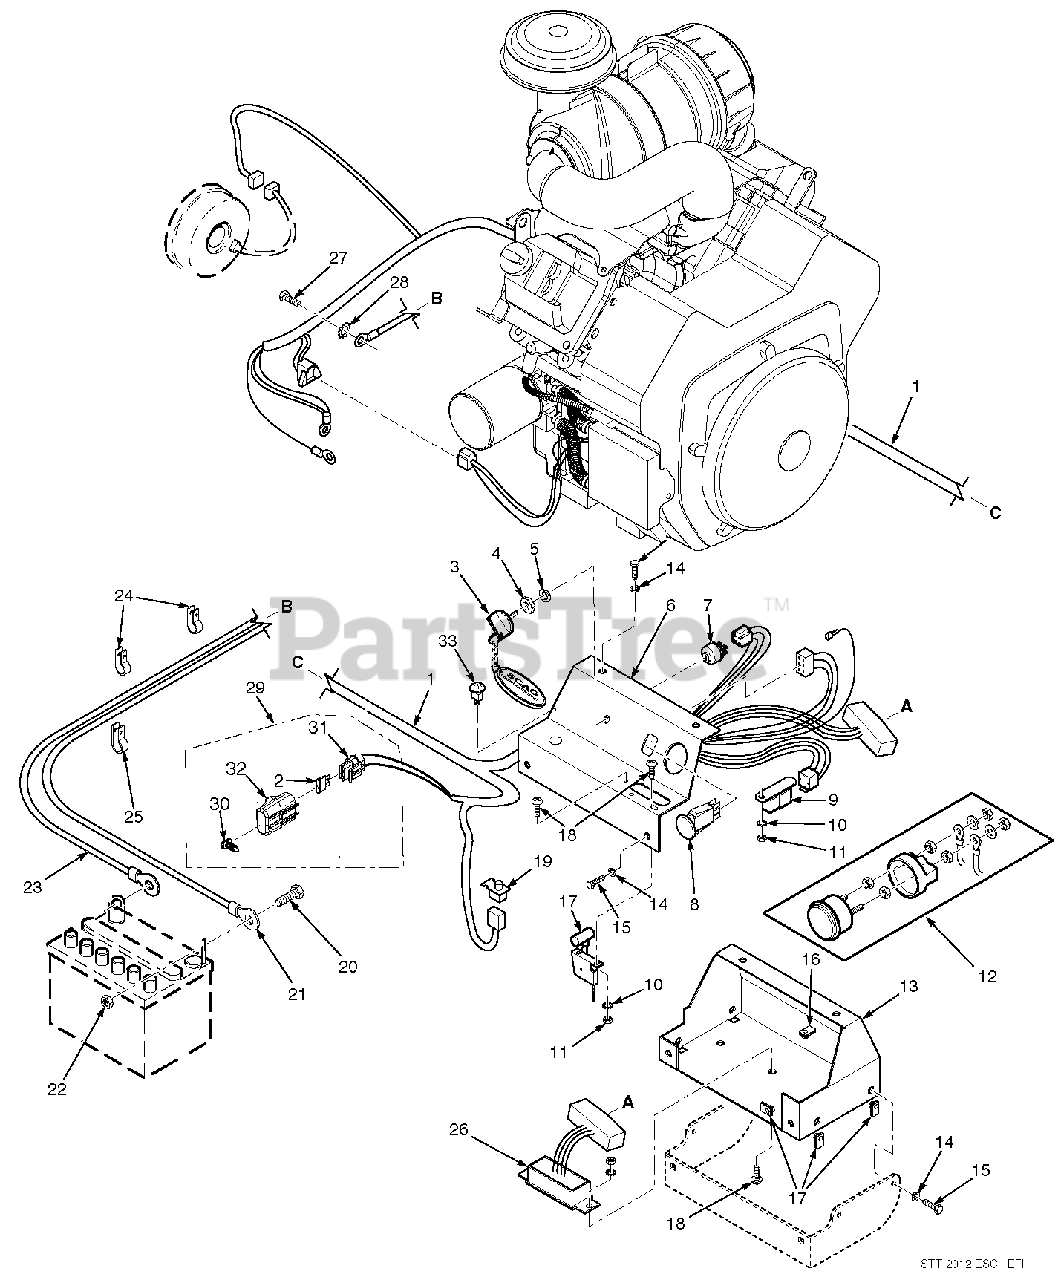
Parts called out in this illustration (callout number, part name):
1	Wire Harness
2	Fuse, 20 AMP
3	Key, Ignition
3	Key Assembly w/Fob
4	Nut, Hex 5/8-32
5	Lockwasher, 5/8" Internal
6	Instrument Panel, Top w/Decals
7	Key Switch
8	Switch, PTO
9	Relay
10	Lockwasher, #10 External Tooth
11	Nut, Hex #10-32
12	Volt Meter
13	Base, Instrument Panel
14	Lockwasher, 1/4"
15	Bolt, Hex Head 1/4-20 x 3/4"
16	U-Nut, 1/4-20
17	Throttle And Choke Controls
18	Screw, Phillips Washer Head #10-32 x 1/2"
19	Switch, Interlock-Seat
20	Bolt, Hex Head 1/4-20 x 1/2"
21	Cable, Battery - Red
22	Nut, Hex 1/4-20
23	Cable, Battery - Black
24	Clamp, Cable 1/2" ID.
25	Clamp, Cable 3/4" ID.
26	Electronic Module
27	Bolt, Hex Head M8-1.25 x 20mm
28	Lockwasher, 5/16" External Tooth
29	Double Fuse Assembly, Sealed
30	Clip, Wire
31	Fuse Holder
32	Cover, Sealed Single
33	Indicator Light
